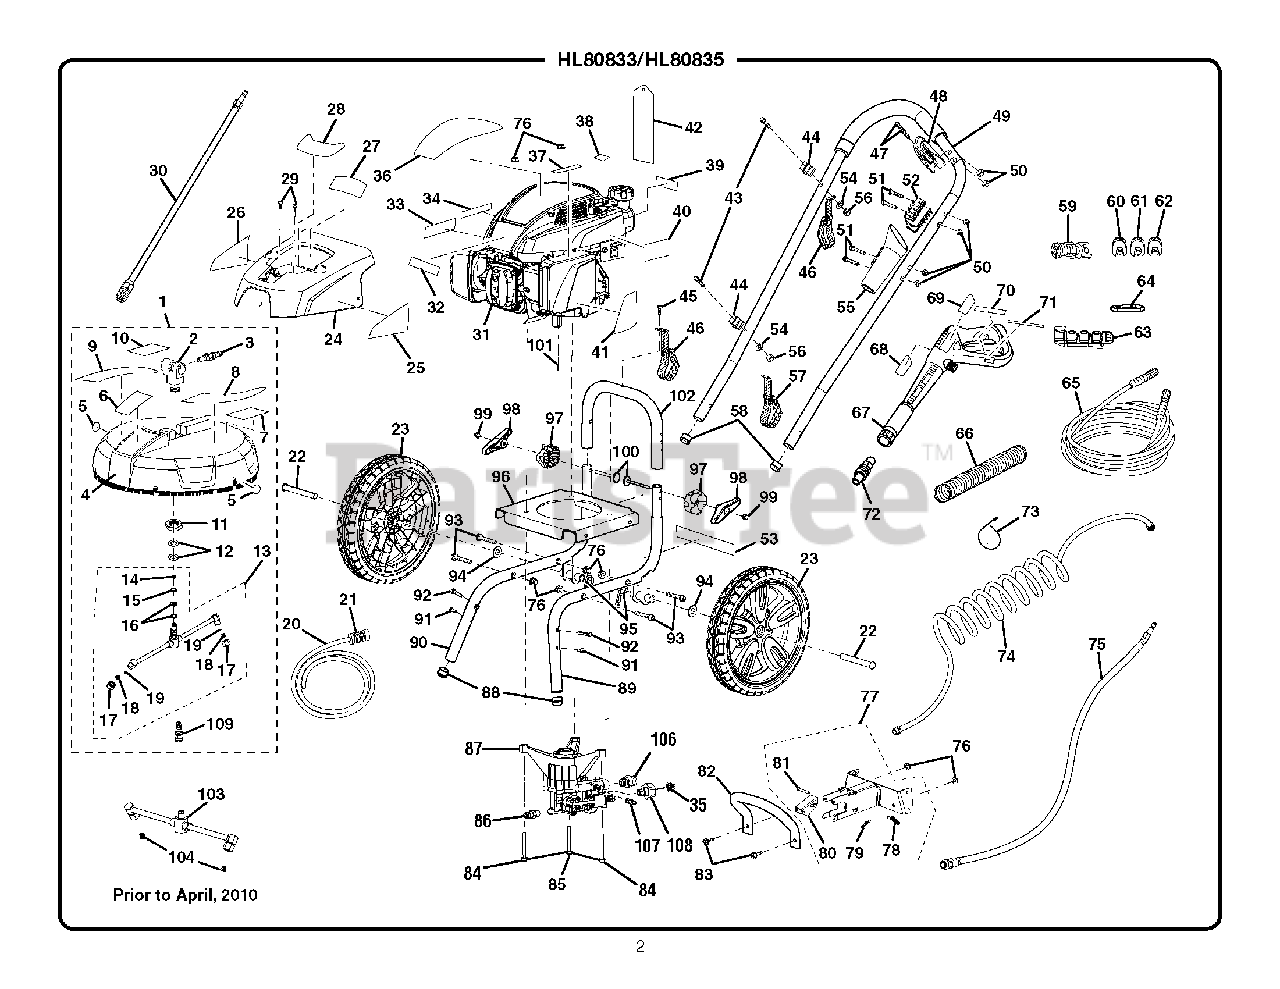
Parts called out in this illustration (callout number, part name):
1	Deck Assembly
2	Deck Pivot Assembly
3	1/8 Quick Connect (BSPP)
4	Deck w/Brush Assembly
5	No Hands/Feet Label
6	Surface Cleaner Label
7	Deck Danger Label (FR)
8	Deck Pressure Washer Label
9	Deck Logo Label
10	Deck Danger Label
11	Nut (M22)
12	Washer (D12.2 x D22 x .8t)
13	Deck Swivel w/Nozzle Assembly
14	O-Ring (4.5 x 1.8)
15	Washer (D17.9 x D13.7 x 1.5t)
16	Washer (D17.9 x D11.1 x 2.9t)
17	Nozzle Nut
18	Nozzle w/015 Jet (1/8 NPT)
19	O-Ring (4.5 x 1.8)
20	Injection Hose
22	Axle (D13.3 x 95 mm)
23	Wheel (12 in. x 2 in.)
24	Front Shroud Assembly
25	Shroud Warning Label (FR)
26	Shroud Warning Label
27	PSI/GPM Performance Label (ENG/FR)
28	Deck Removal Label
29	Screw (12-24)
30	Wand Assembly
31	Homelite Engine
32	Logo Label (Homelite)
33	Hot Surface Label
34	EMC Label
35	Filter Screen
36	Performance Label
37	Homelite Inquires Label
38	E85 Label
39	Combustion Warning Label
40	Start/Run/Choke Label
41	Quick Start Label
42	Danger Hang Tag Label
43	Bolt (M5 x 40 mm)
44	Spring Clip
45	Screw (12-14 x 1/2 in., Pan Hd.)
46	Hose Storage Strap
47	Screw (1/4-20 x 40 mm, Hex Hd.)
48	Trigger Handle Lock
49	Upper Handle Assembly
50	Lock Nut (1/4-20)
51	Screw (1/4-20 x 45 mm, Truss Hd.)
52	Upper Trigger Handle Holder
53	Data Label
54	Washer (D15 x D5.5 x 2t)
55	Lower Trigger Handle Holder
56	Lock Nut (M5)
57	Hose Attachment System Strap
58	End Cap (25 mm)
59	Soap Blaster Nozzle Assembly
60	0º Nozzle
61	40º Nozzle
62	25º Nozzle
63	Nozzle Holder
64	Spring Clip
65	Hose
66	Tube Conduit
67	Trigger Handle Assembly
68	Logo Label (Homelite Trigger Handle)
69	Warning Label (ENG)
70	Warning Label (FR/SP)
71	Maximum Pressure Label
72	Expand Style Quick Connect
74	15 ft. Self-Coiling Garden Hose
75	Deck High Pressure Hose Assembly
76	Lock Nut (M8 x 1-1/4 mm)
77	Deck Bracket Assembly
78	Deck Lock Spring
79	Hitch Pin
80	Release Handle
81	Connect Pin
82	Lift Handle
83	Hex Bolt (M8 x 20 mm)
84	Hex Bolt (M8 x 60 mm)
85	Bolt (M8 x 40 mm, Hex Hd.)
86	Thermal Release Valve
87	Pump (Himore)
88	Frame Glide
89	Left Frame Assembly
90	Right Frame Assembly
91	Screw (T-30 Torx, 1/4-20, Truss Hd. Shoulder)
92	Screw (1/4-20 x 40 mm, T-30 Torx Flat Hd.)
93	Hex Bolt (M8 x 50 mm, Flange Hd.)
94	Washer (1/2 in.)
95	Hitch Pin
96	Engine Plate
97	Handle Spacer
98	Knob Assembly
99	Acorn Nut (Center lock)
100	Carriage Bolt (1/4-20 x 88.5 mm)
101	Output Shaft Key
102	Frame Connector Assembly
103	Deck Swivel w/Nozzle Assembly
104	Nozzle w/015 Jet (1/8 NPT)
106	Outlet Tube
107	Detergent Suction Kit
108	Inlet Tube
